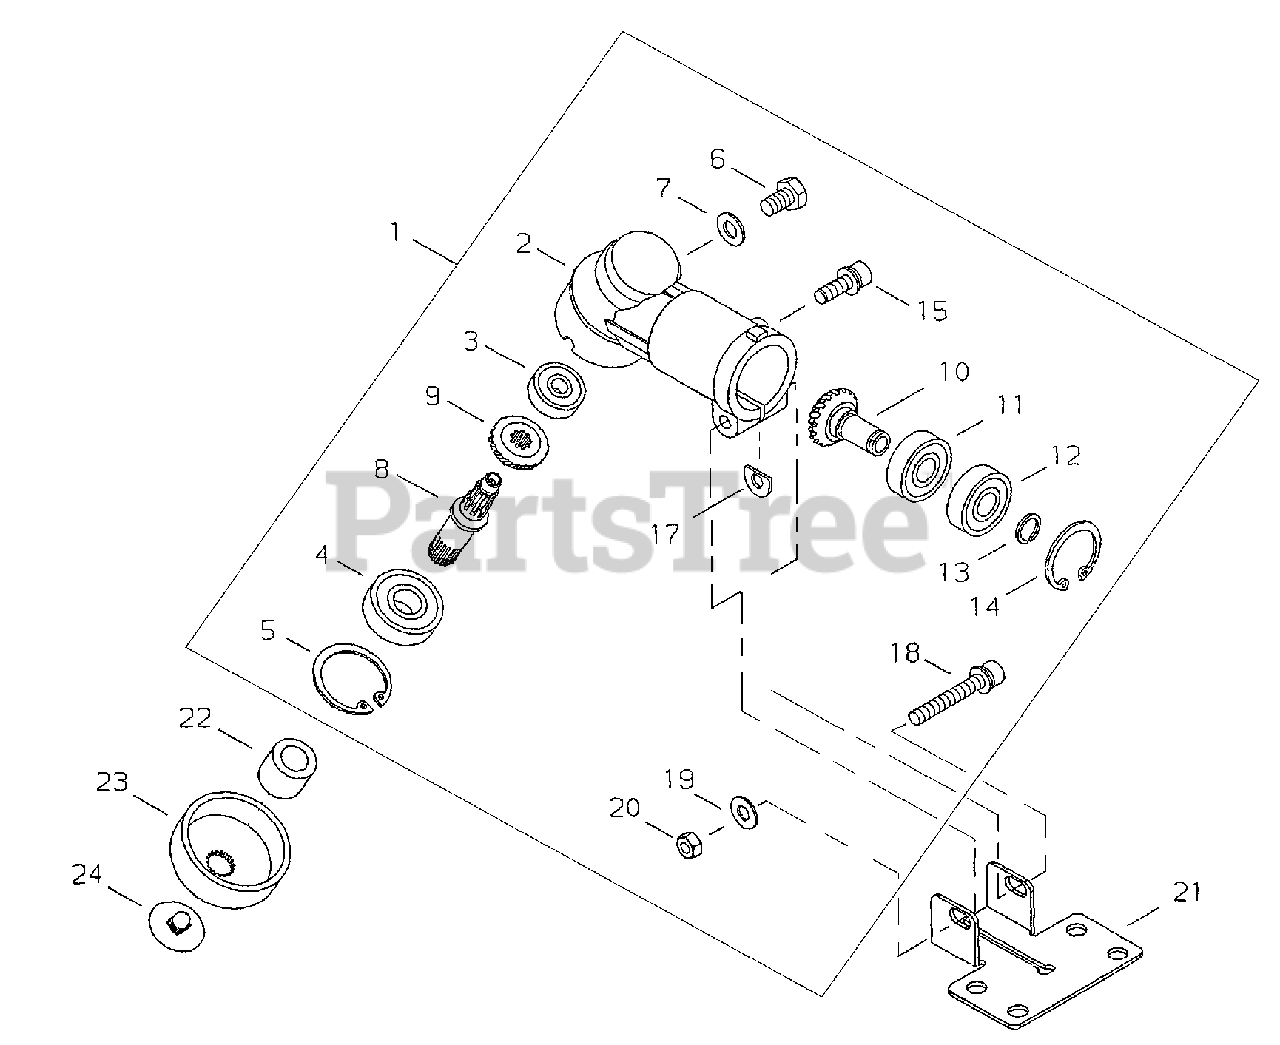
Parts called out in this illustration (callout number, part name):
2	HOUSING, GEAR CASE
3	BEARING, BALL 626
4	BEARING, BALL 6000DDU
5	RING, SNAP Ø26
6	BOLT M6×10
7	WASHER
8	SHAFT, GEAR
9	GEAR, BEVEL
10	GEAR, PINION
10-1	GEAR CASE ASSY
11	BEARING, BALL 608
12	BEARING, BALL 608ZZ
13	RING, SNAP
14	RING, SNAP Ø22
15	BOLT M5×16
17	D-WASHER
18	BOLT M5×35
19	WASHER 5 MM
20	NUT M5
21	PLATE, SHIELD MOUNTING
22	COLLAR
23	HOLDER
24	CLIP
